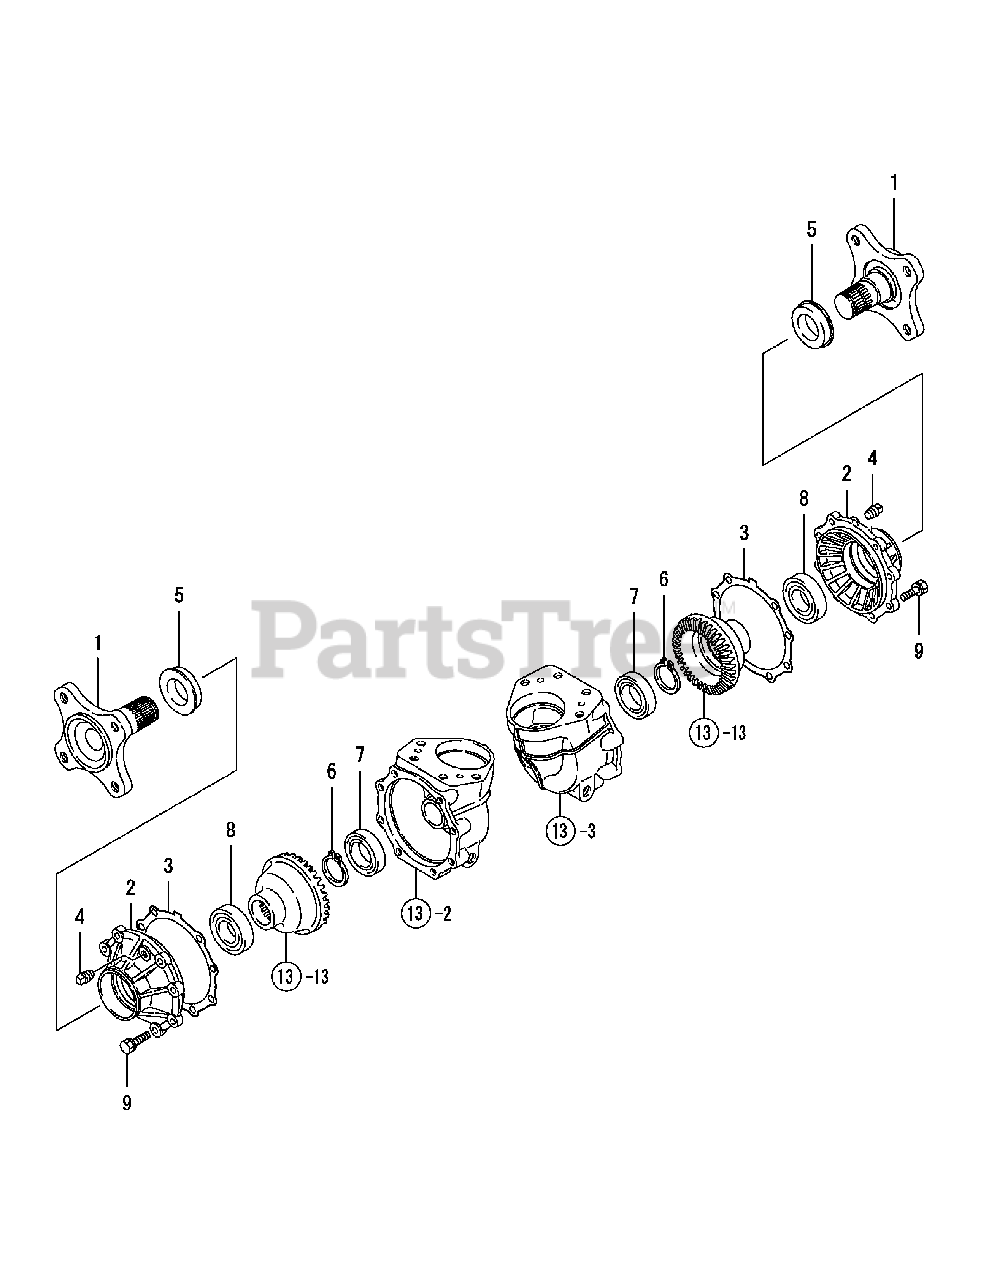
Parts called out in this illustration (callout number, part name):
1	Shaft, Front Axle
2	Case, Front Bearing
3	Packing, Bearing Case
5	Seal 40X62X14, Oil
